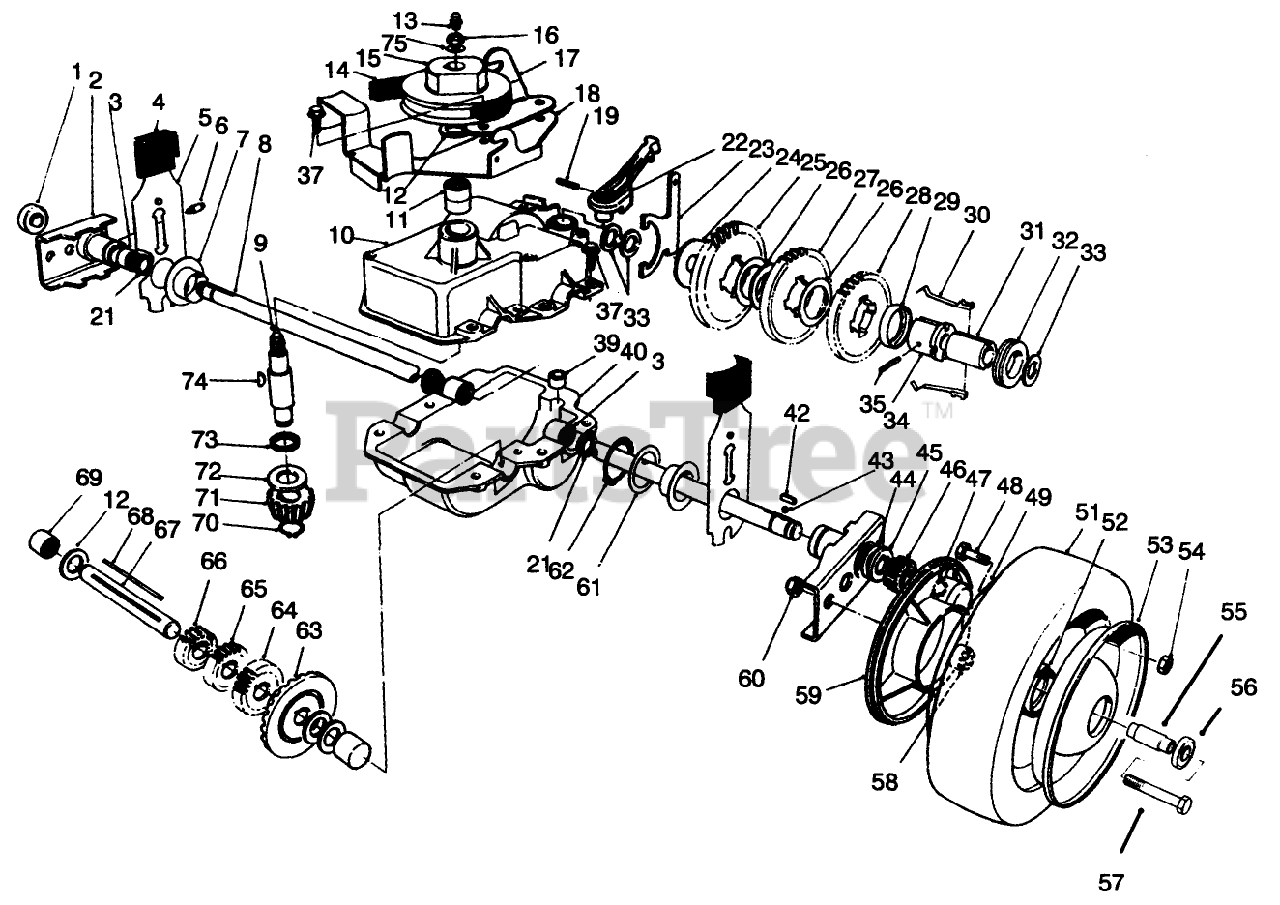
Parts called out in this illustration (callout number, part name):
1	BEARING-WHEEL
2	PIVOT ARM ASM
4	KNOB-ARM
5	REAR SPRING ARM ASM
7	CAP-END
8	SHAFT-OUTPUT
9	INPUT SHAFT ASM
10	UPPER GEARCASE ASM
11	BEARING-NEEDLE
12	WASHER-THRUST
13	FITTING-GREASE, ZERK
14	V-BELT
15	PULLEY
16	NUT-HEX
19	PIN-SPRING
21	SEAL-OIL
22	LEVER-SHIFT
23	YOKE-SHIFT
24	WASHER
26	WASHER
27	GEAR-42T
28	GEAR-38T
29	RETAINER-KEY
30	KEY-SHIFT
31	SLEEVE
32	COLLAR-SHIFT
33	WASHER-PLAIN
34	SLEEVE-GEAR
35	PIN-GROOVE
37	SCREW-HWHTF
39	BUSHING-YOKE
43	SPRING-COMPRESSION
44	WASHER-THRUST, OUTER
45	WASHER-THRUST, OUTER
46	GEAR-PINION
47	RING-RETAINING
48	SCREW-HH
52	HUB-BEARING
54	NUT-LOCK, NI
55	SPACER-BEARING
56	BEARING-WHEEL
57	SCREW-HH
58	SPACER-COVER, WHEEL
59	COVER-WHEEL
60	NUT-LOCK, CONE
61	WASHER
62	RING-RETAINING
63	GEAR-BEVEL
64	GEAR-18T
65	GEAR-14T
66	GEAR-12T
67	SHAFT-INTERMEDIATE
69	BEARING-NEEDLE, CLOSED
70	RING-RETAINING
71	PINION-BEVEL
72	WASHER-THRUST
74	KEY-WOODRUFF
75	WASHER-FLAT
